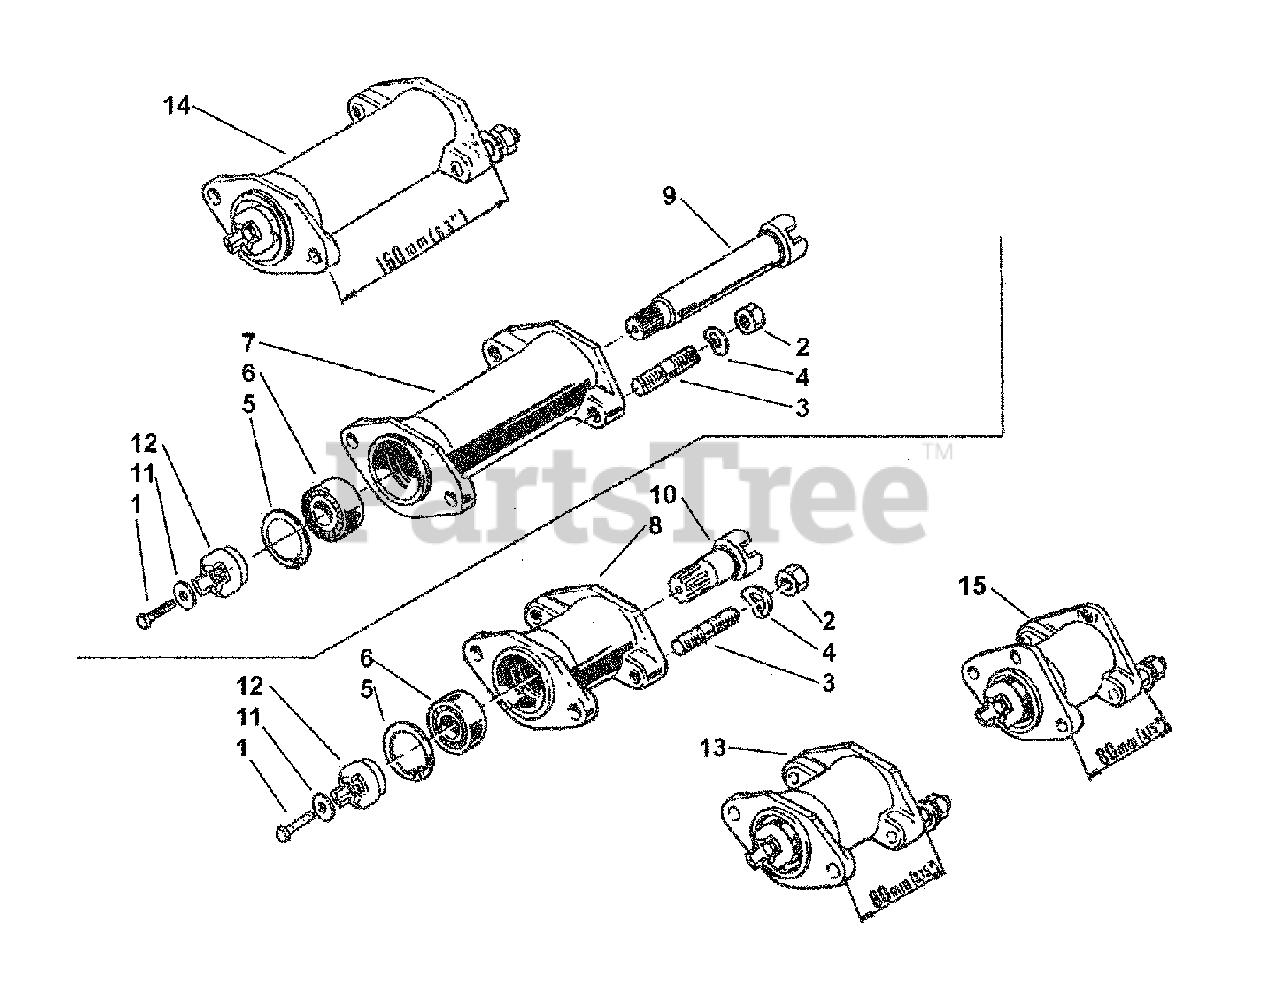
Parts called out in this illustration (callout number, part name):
1	SCREW, M6X16
2	NUT M12 X 1.25 UNI 5587 6S
3	STUD 56XM12X1.25X26XM12X22 8G
4	WASHER, LOCK 13
5	CIRCLIP, INTERN. D 47
6	BEARING 25 X 47 X 12 2RS 6005
7	EXTENSION BODY 160 MM
8	EXTENSION BODY
9	EXTENSION SHAFT
10	EXTENSION SHAFT
11	WASHER, SPECIAL
13	PTO EXTENSION 3"
14	PTO EXTENSION 6"
15	PTO EXTENSION 3"
